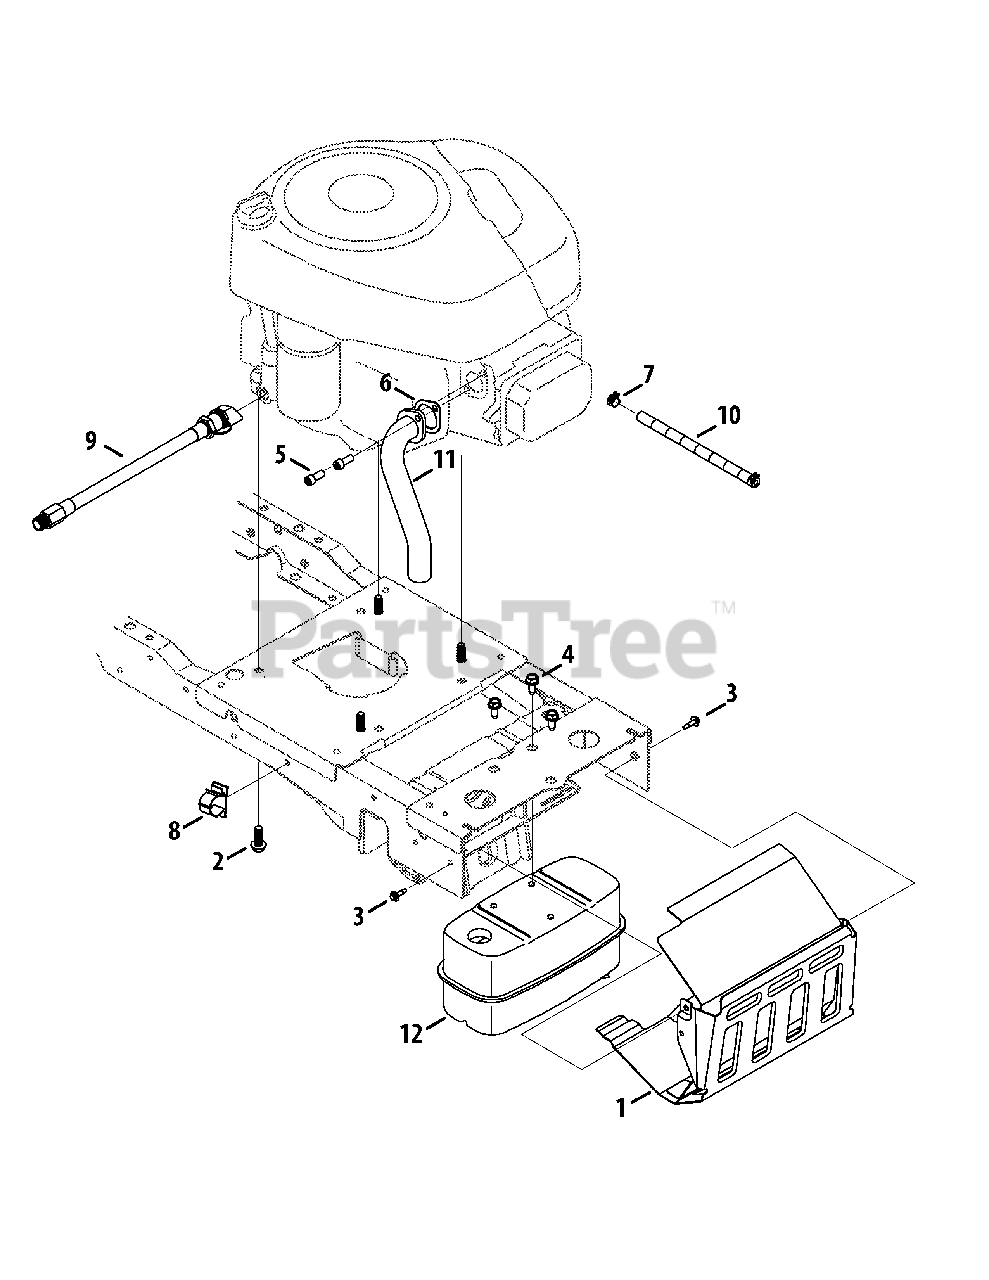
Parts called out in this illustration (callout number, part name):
1	Shield Ass’y, Muffler
2	Screw, Self-tapping, 3/8-16, 1.0
3	Screw, M6-1 x .625
4	Screw, Self-tapping, M8-1.25, .750
5	Screw, Sokt Head, 5/16-18, .750
6	Exhaust Gasket
7	Clamp, Hose, .490 Dia.
8	Push Mount Wire Clip, .750
9	Drain, Oil
10	Hose, Fuel, Low Permeation, 1/4
11	Exhaust Pipe, LH
12	Muffler
